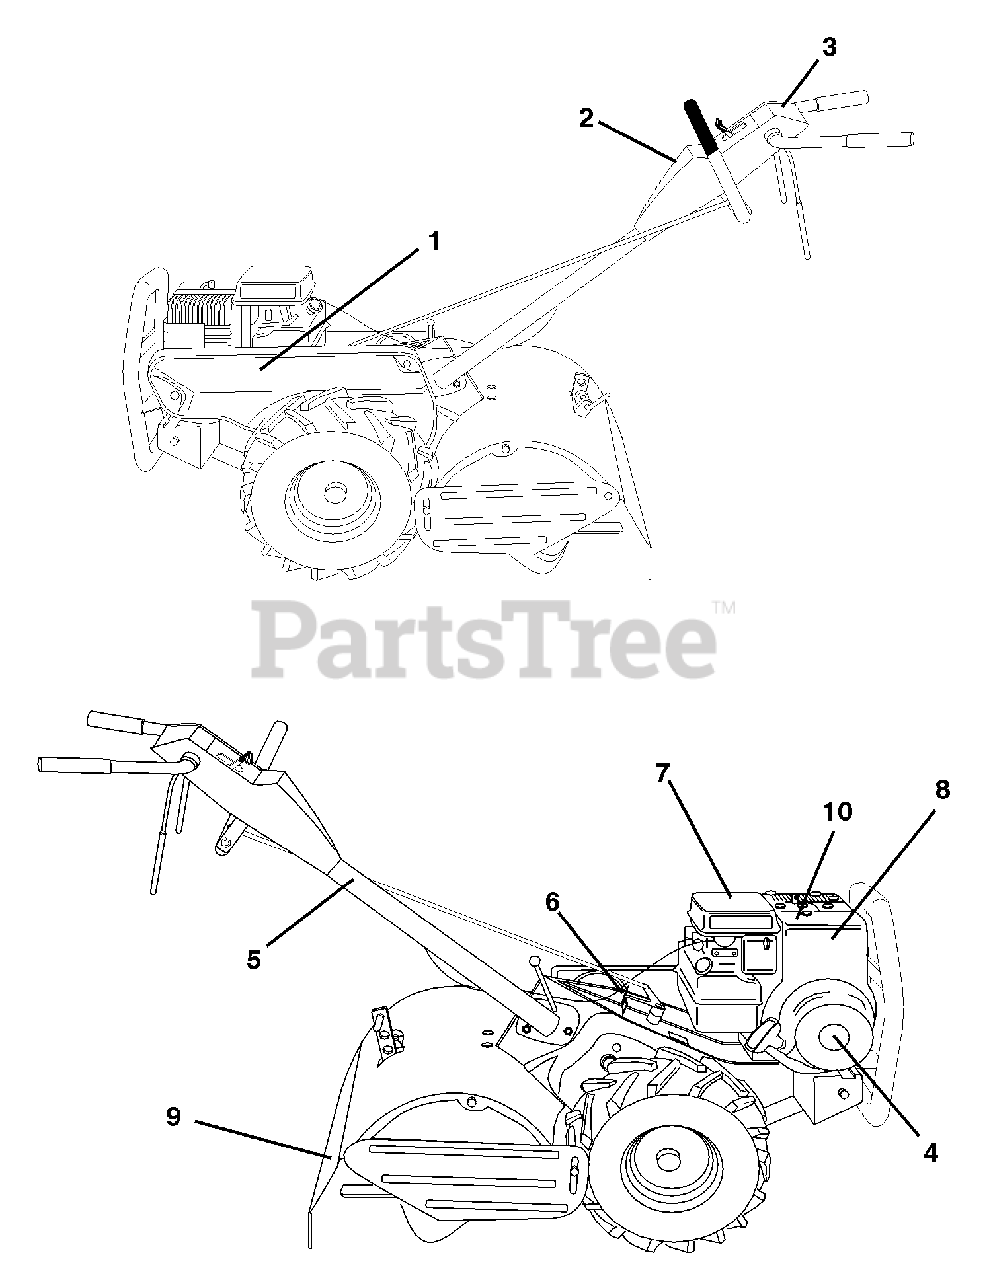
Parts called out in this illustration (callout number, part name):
1	Decal, Logo
2	Decal, Logo
3	Decal, Logo
4	Decal, 5.5 HP
5	Decal, Hand Placement
6	Decal, Shift Indicator
7	Decal, Caution
8	Decal, Briggs & Stratton
9	Decal, Warning, Rotating Tines
10	Decal, Tick Mark
